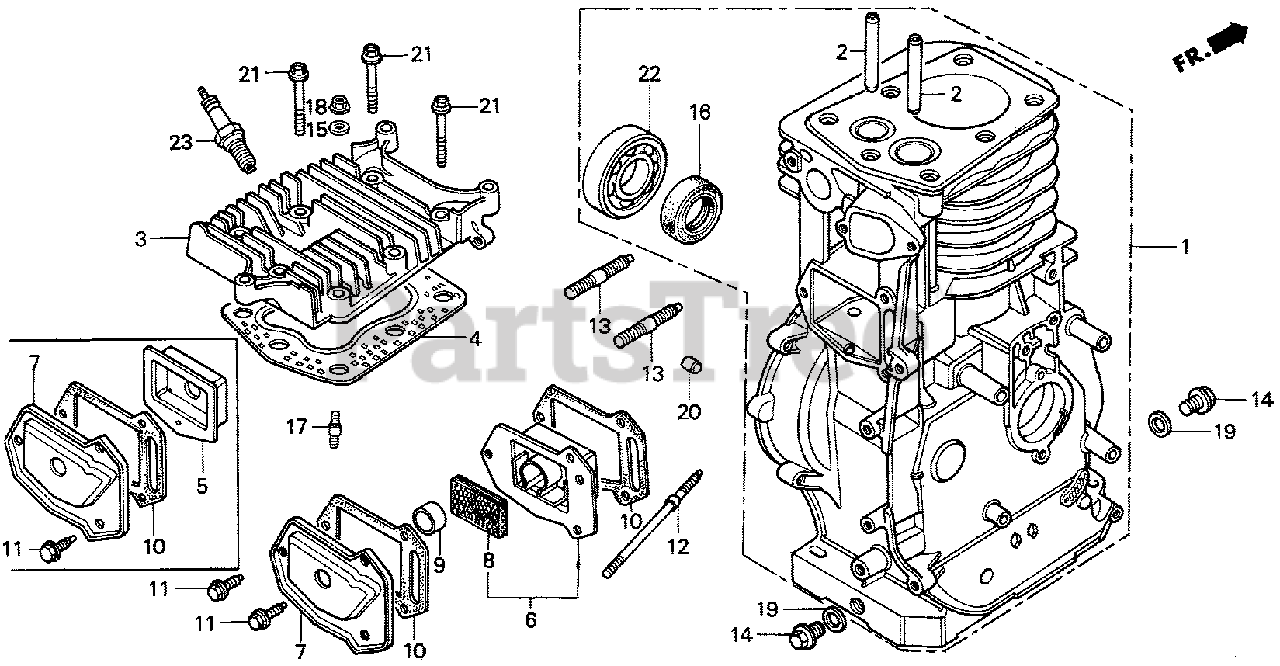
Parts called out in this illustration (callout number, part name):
1	CYLINDER ASSY. (NOT AVAILABLE)
2	GUIDE, VALVE (OS)
3	CYLINDER HEAD
4	GASKET, CYLINDER HEAD
6	CASE, BREATHER
7	COVER, TAPPET ROOM
8	FILTER, BREATHER
9	SEAL, BREATHER
10	GASKET, TAPPET COVER
11	BOLT, FLANGE (6X12) (CT200)
12	BOLT, STUD (6X96)
13	BOLT, STUD (8X35)
14	BOLT, DRAIN PLUG
15	WASHER (8X22)
16	OIL SEAL (25X41X6)
17	BOLT, STUD (8X40)
18	NUT-WASHER (8MM)
19	WASHER, DRAIN PLUG (12MM)
20	PIN A, DOWEL (8X14)
21	BOLT, FLANGE (8X45)
22	BEARING, RADIAL BALL (6205)
23	SPARK PLUG (BR-4HS) (NGK)
23	SPARK PLUG (W14FR-U) (DENSO)
